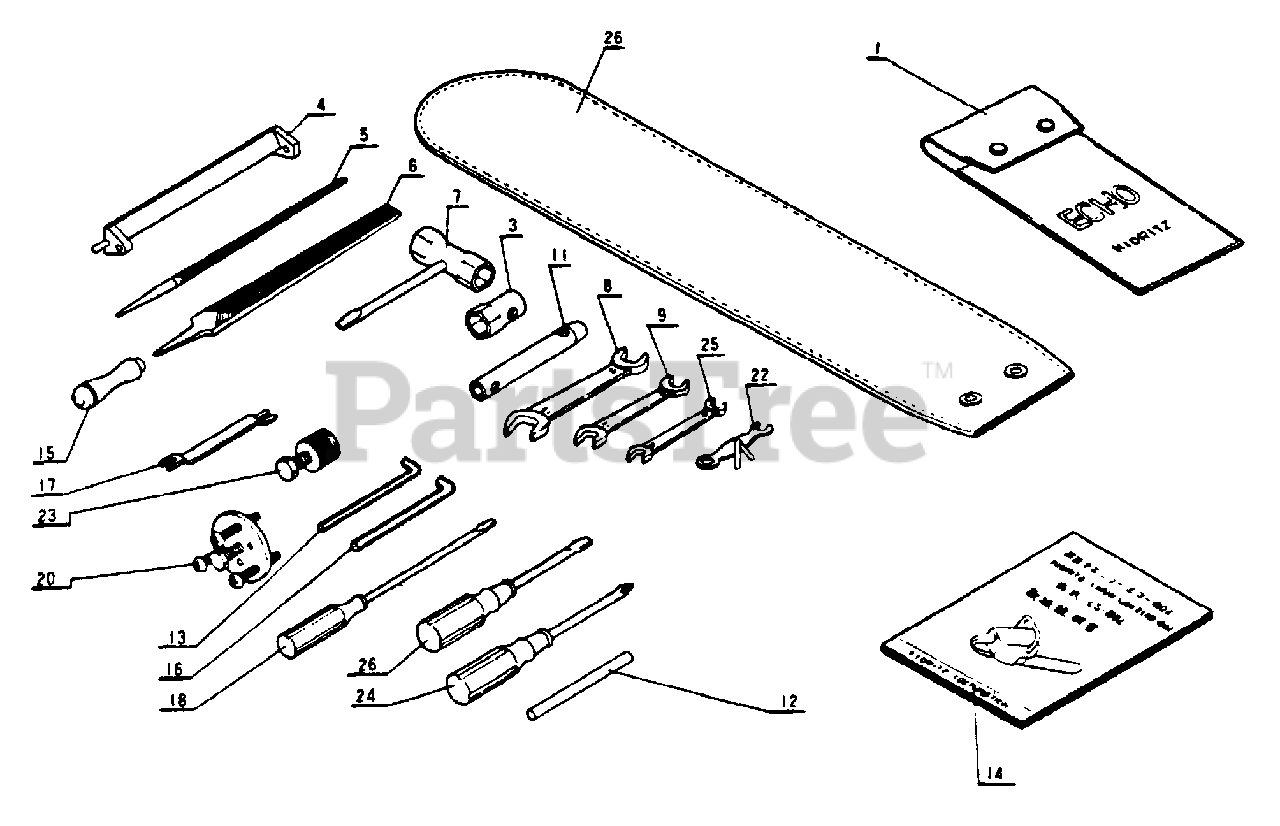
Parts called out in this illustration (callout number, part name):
1	BAG, TOOL
3	BOX SPANNER - 17
4	FILE HOLDER
5	ROUND FILE
6	FLAT FILE
7	BOX WRENCH W/DRIVER
7	T-WRENCH 13×19×180
8	SPANNER
9	SPANNER 8×10
9	SPANNER 8×9
11	BOX WRENCH
11	WRENCH 8×10
12	ROD, HANDLE
13	WRENCH, ALLEN 4 MM
14	OWNER'S MANUAL
15	FILE GRIP
16	WRENCH, ALLEN 5 MM
17	GAUGE, DEPTH
18	SCREWDRIVER, SLOTTED
20	PULLER (CLUTCH)
22	MAGNETO SPANNER
23	PULLER (MAGNETO)
24	SCREWDRIVER - CROSS HEAD
25	SPANNER
26	COVER, CHAIN
